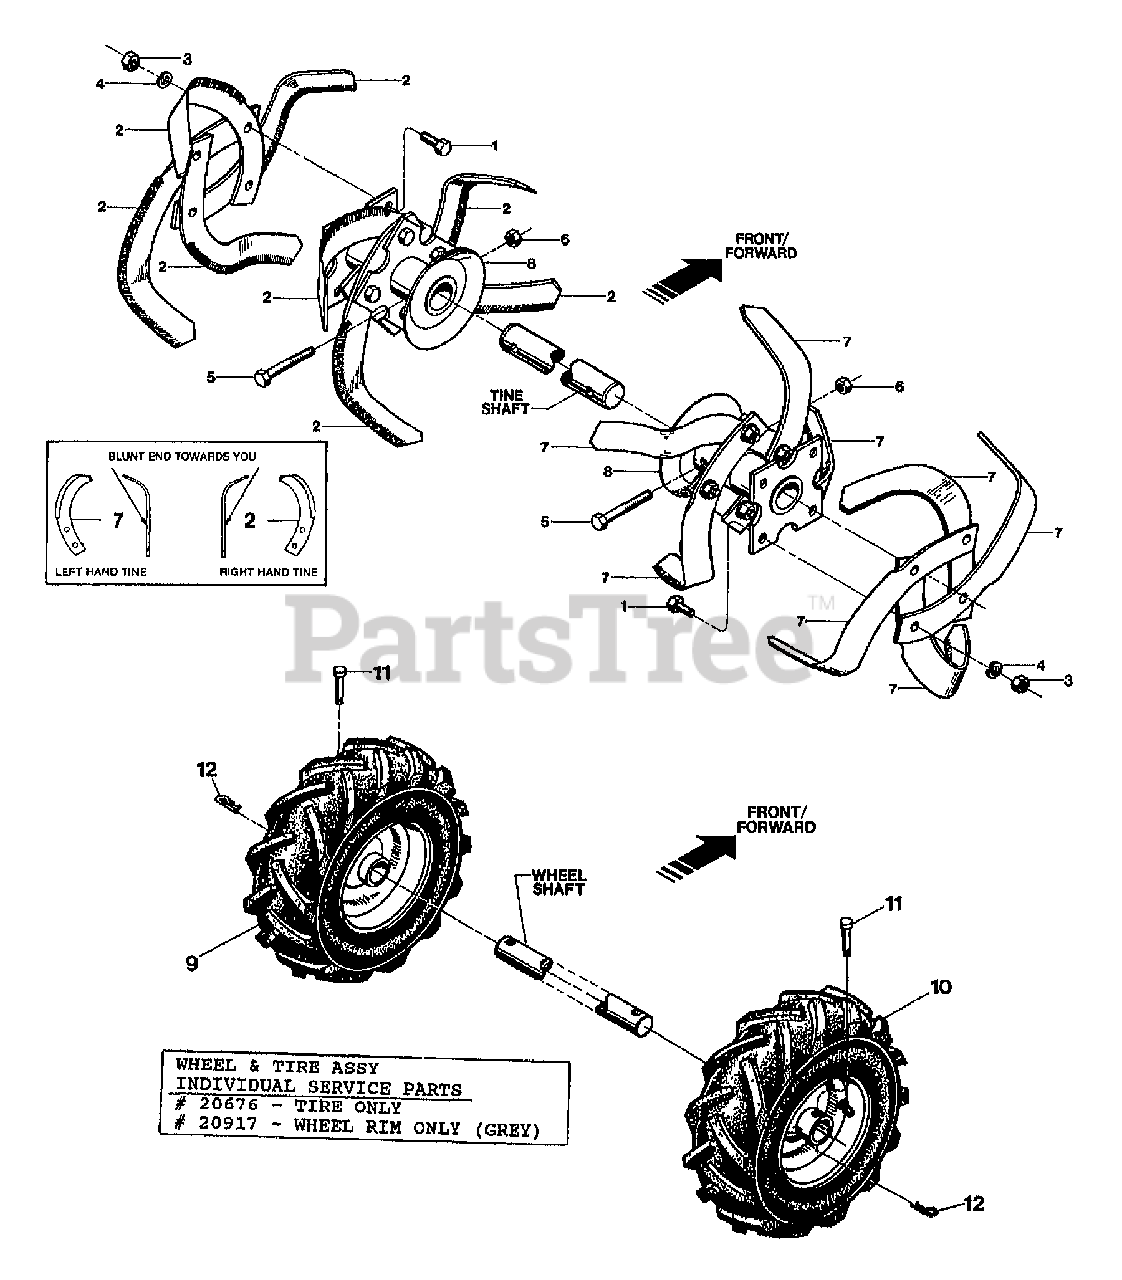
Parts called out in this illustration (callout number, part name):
1	SCR-HH 3/8-16X1.0 G5 ZP
2	TINE-BOLO RT W/HDW
3	NUT-HEX 3/8-16 ZP
4	WASHER-LK .375 @ DEPL
5	SCR-HH 3/8-16X2.00 G8
6	NUT-H/LK 3/8-16
7	TINE-BOLO LT W/HDW
8	HOLDER-TINE PONY
9	ASSM-TIRE&WHL LH GRAY
9	ASSM-TIRE LT 4.10 X 6"
10	ASSM-TIRE&WHL RH GRAY
10	ASSM-TIRE RT 4.10 X 6"
11	PIN-CLEVIS
12	PIN-CLIP .08
